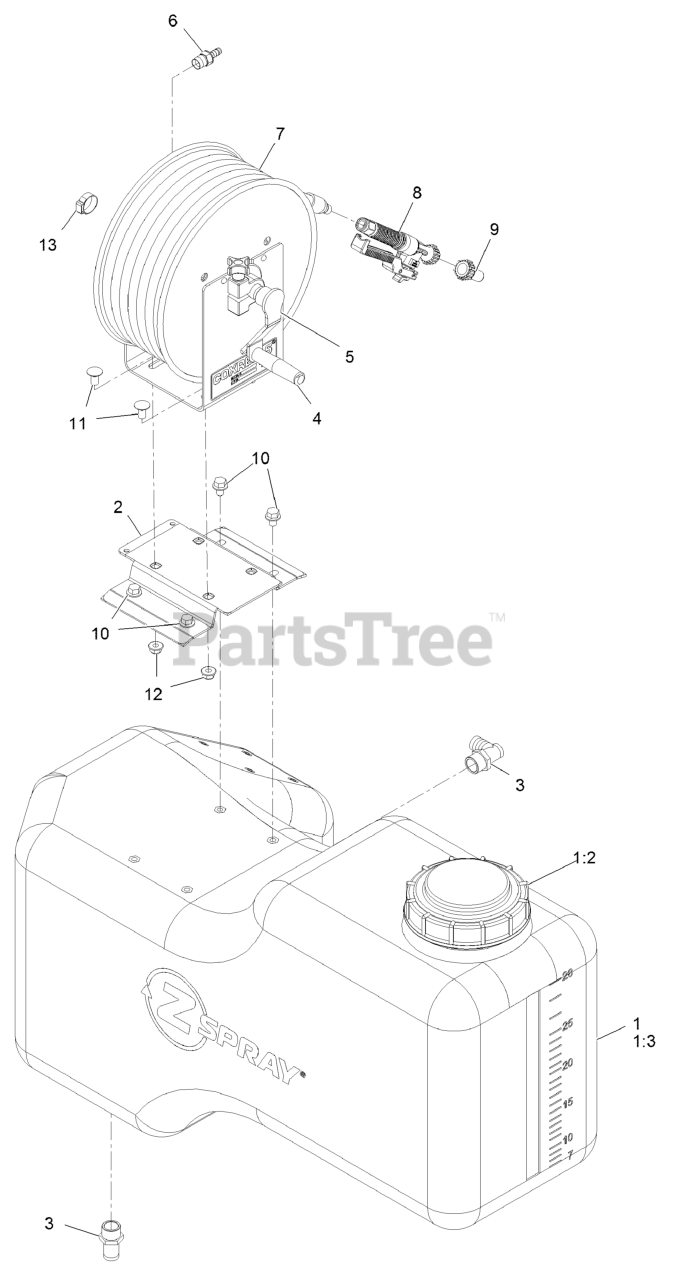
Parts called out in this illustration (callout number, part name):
1	ASM-TANK, LT
1:2	CAP-TANK, SPRAY
1:3	FITTING-BULKHEAD
2	MOUNT-REEL, HOSE
3	FITTING-ELBOW, 90
4	REEL-HOSE
5	Crank-Reel
6	FITTING,MALE
7	HOSE-SPRAY, 75'
8	GUN-SPRAY, SPOT
9	TIP-SPRAY, #12 SPOT
10	Screw-HHF
11	SCREW-CARRIAGE
12	Nut-Hex Flange
13	CLAMP-OETIKER, 167
